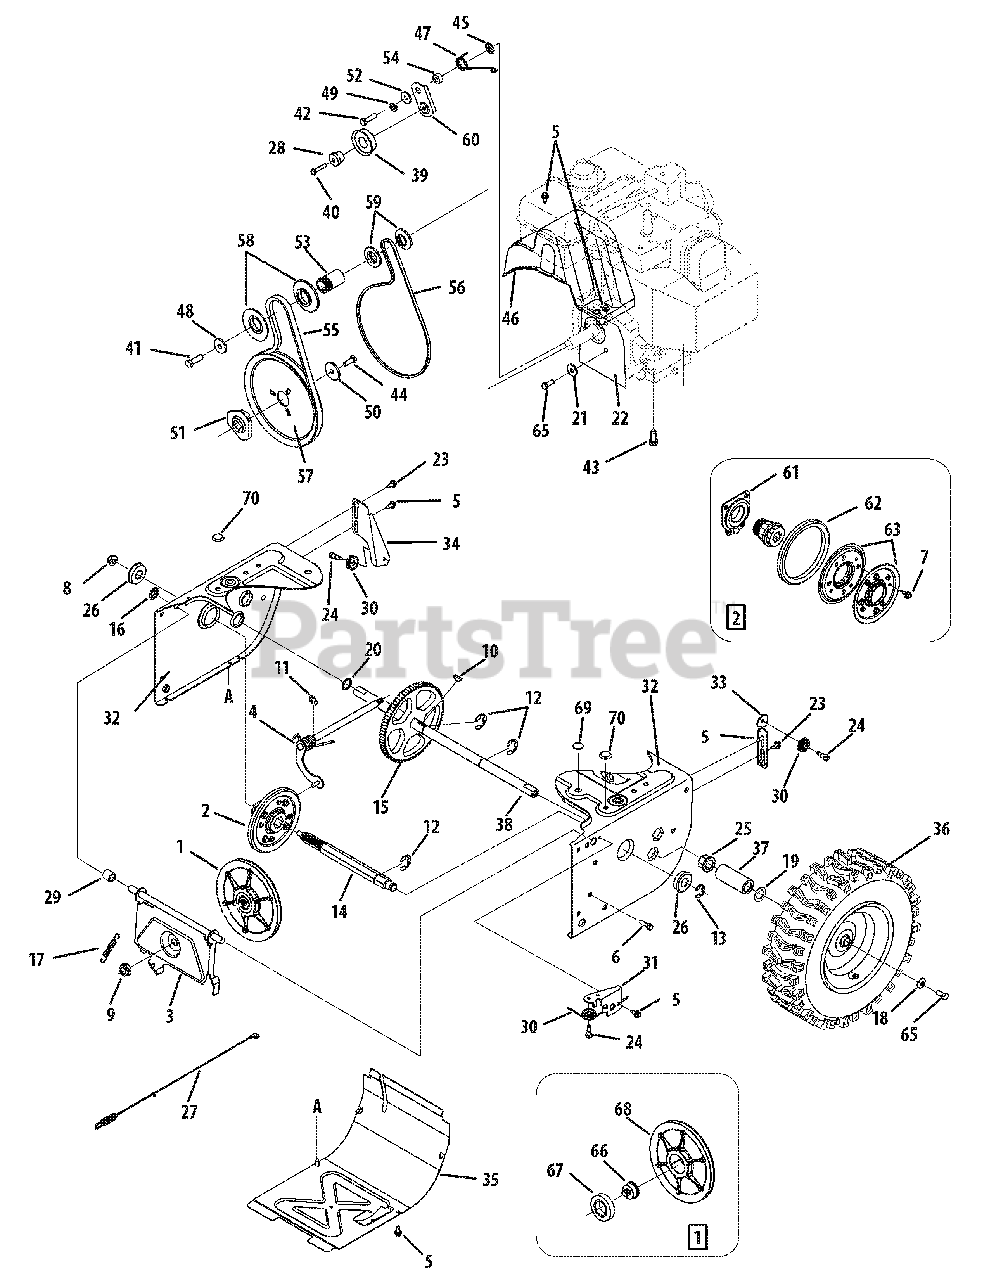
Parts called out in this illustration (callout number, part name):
1	Disc Assembly, Friction Wheel
2	Friction Wheel Assembly, 5.5 OD
3	Friction Wheel Support Bracket
4	Rod Shift Assembly
5	Hex Screw, 5/16-24 x .750
6	Screw, 1/4-20 x 1.000
7	Screw, 1/4-20 x .625
8	Flange Lock Nut, 3/8-16, Nylon
9	Jam Lock Nut, 5/8-18, Nylon
10	Hi-pro Key, 3/16 x 3/4 Dia.
11	E-ring, .750 Dia.
12	Retaining E-ring, .875 Dia.
13	E-ring, .750 Dia.
14	Hex Shaft, .8125, 7-Tooth
15	Gear, 80-Tooth
16	Speed Nut, .500
17	Extension Spring
18	Bell Washer, .340 x .872 x .060
19	Flat Washer, .793 x 1.24 x .060
20	Flat Washer, .75 x 1.00 x .060
21	Shoulder Space
22	Cover Plate
23	Shoulder Screw, .37 x .105, 1/4-20
24	Screw, 1/4-28, .375
25	Hex Flange Bearing
26	Ball Bearing, 17 x 40 x 12
27	Wheel Clutch Cable, 44.95"
28	Shoulder Space, .26 x .79 x .538
29	Spacer, .508 ID x .75 OD x .68
30	Cable Roller
31	Auger Cable Front Guide Bracket
32	Frame
33	Auger Cable Guide Bracket
34	Drive Cable Guide Bracket
36	X-Trac Wheel Assy., LH, 15 x 5 x 6
36	X-Trac Wheel Assy., RH, 15 x 5 x 6
37	Spacer, 1.25 x .75 x 3.0
38	Axle, .75 x 22"
39	Idler Pulley Assembly
40	Hex Screw, 1/4-20 x 1.25
41	Hex Screw, 3/8-24 x 1.25
42	Hex Screw, 5/16-24 x 1.25
43	Sems Screw, 3/8-16 x 1.00
44	Hex Screw, 5/16-24 x .875
45	Push-on Nut, .25 Dia.
46	Belt Cover
47	Torsion Spring, .850 ID x .354
48	Flat Washer, .406 x 1.25 x .157
49	Lock Washer, .3125
50	Flat Washer, .34 x 1.50 x .150
51	Adapter Pulley, .75 Dia.
52	Shoulder Spacer, .317 x .50 x .102
53	Spacer, .875 ID x 1.185 OD
54	Spacer, .340 x .750 x .360
55	Auger Drive Belt
56	Wheel Drive Belt
57	Auger Drive Pulley, 8.1 x .5
58	Pulley Half, V x 2.600 OD
59	Pulley Half, 1/4-V x 1.5 OD
60	Wheel Drive Idler Bracket
61	Bearing Assembly
62	Friction Wheel Rubber
63	Friction Wheel Plate
65	Hex Screw, 5/16-24 x .750
66	Disc Bearing Friction Pin
67	Ball Bearing, 30 x 55 x 13
68	Friction Wheel Disc, .060 x 8.0
69	Plug, 1/2 ID
70	Plug, 3/8 ID
